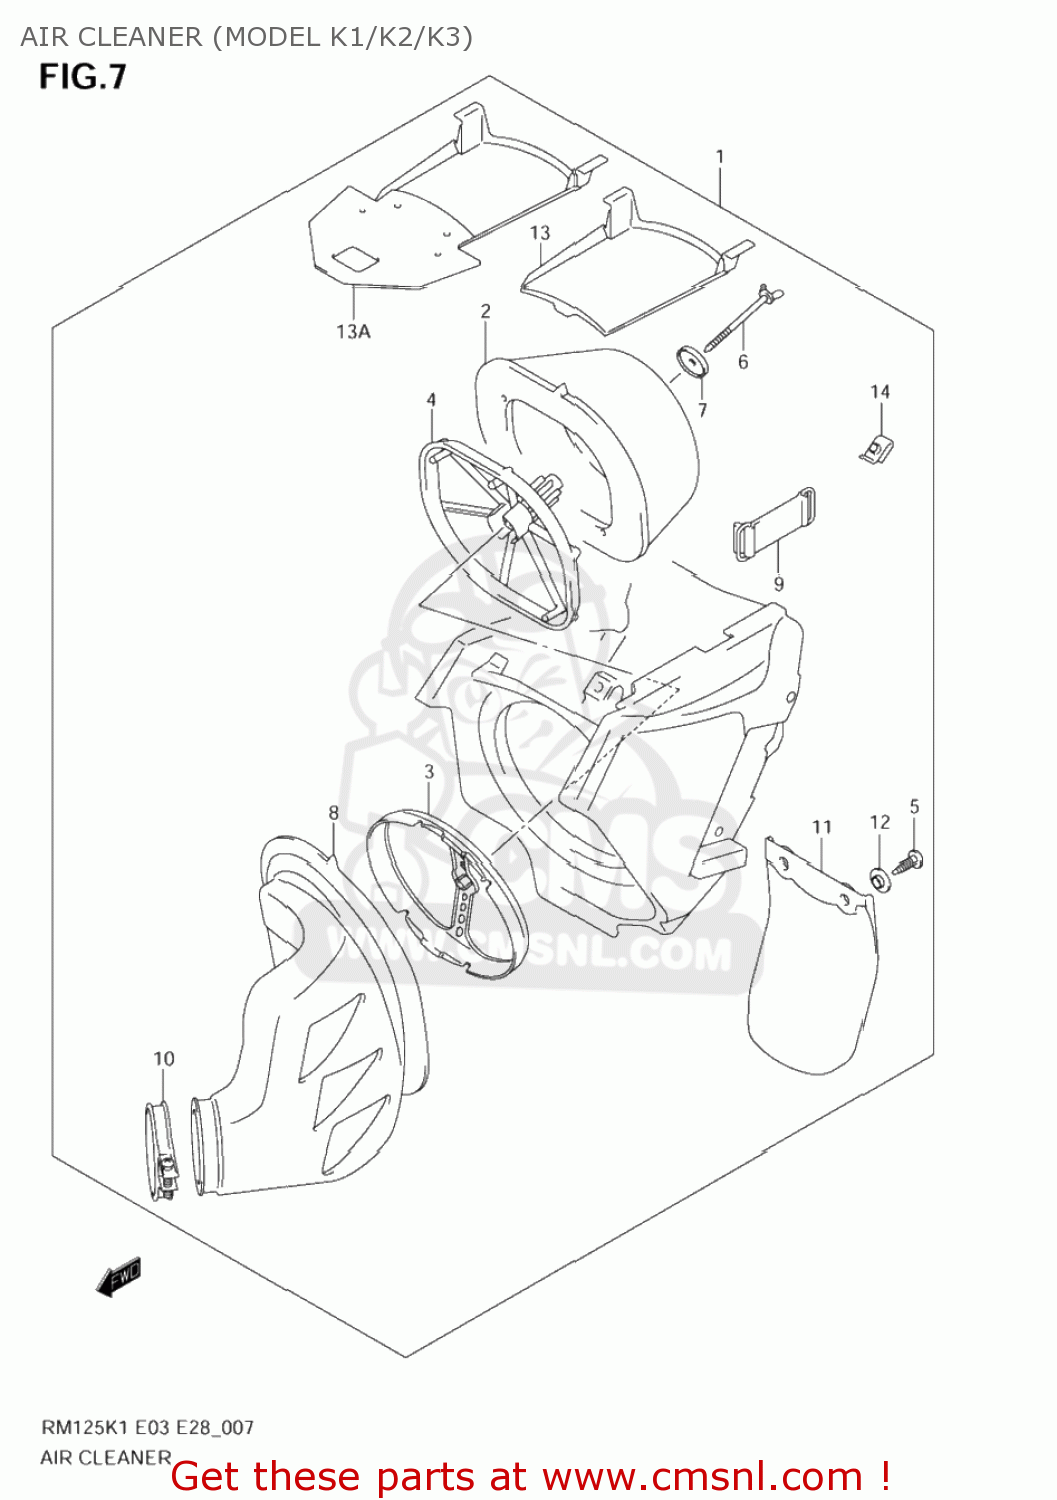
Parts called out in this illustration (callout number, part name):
1	CLEANER ASSY,AIR
2	FILTER ASSY
3	BASE,FILTER
4	HOLDER,FILTER
5	SCREW
6	BOLT,WING
7	WASHER,AIR CLEANER
8	TUBE,OUTLET
9	BAND(L:65)
10	CLAMP
11	MUDGUARD
12	COLLAR
13	CAP,AIR CLEANER
13A	CAP,AIR CLEANER
14	HOLDER,REAR BU
